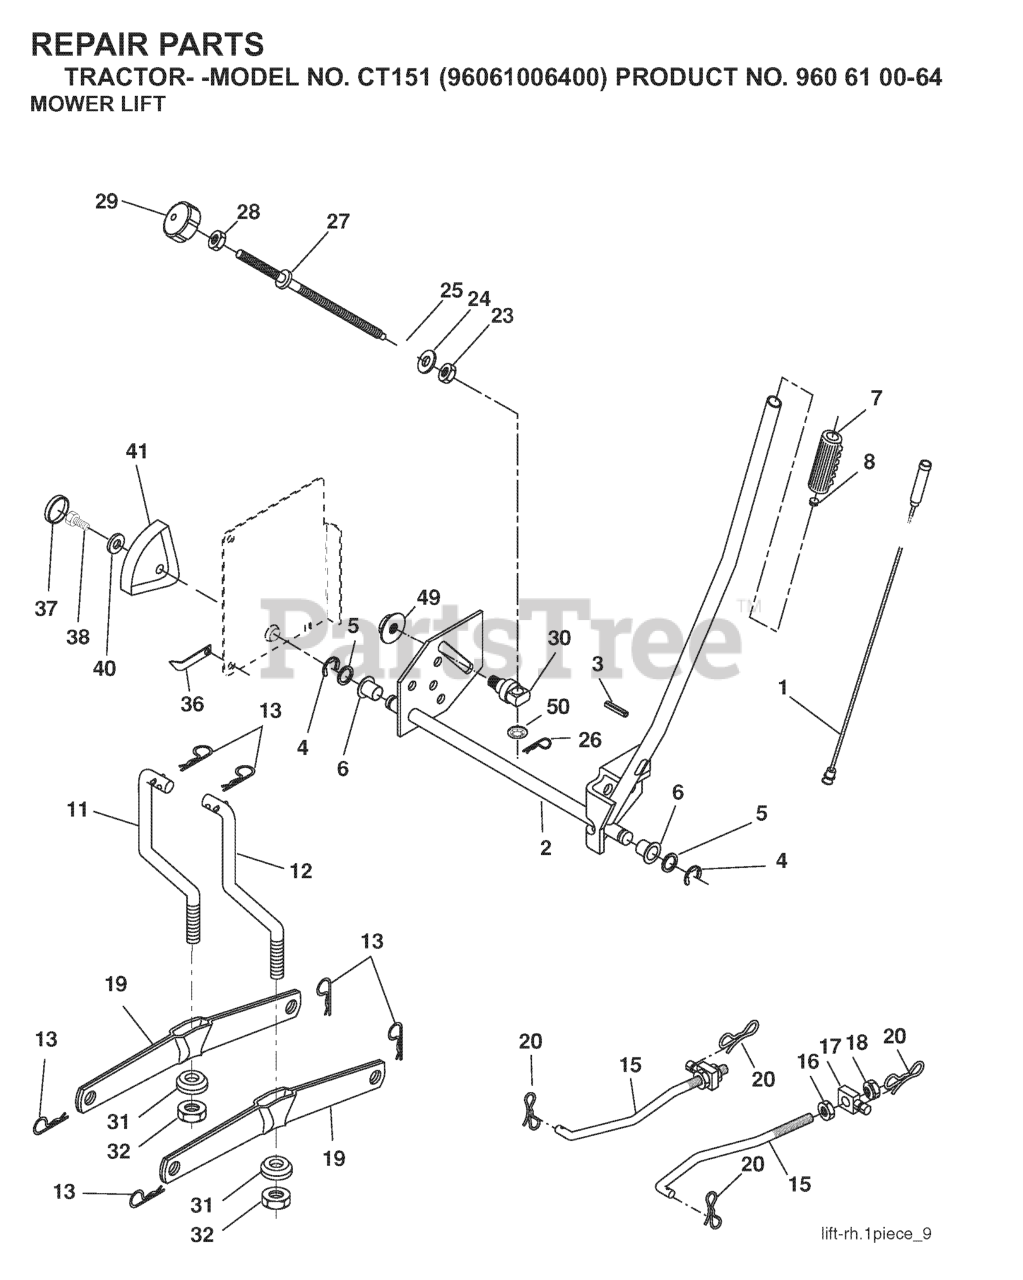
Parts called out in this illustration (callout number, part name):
1	WIRE ASM INNER W/ PLUNGER LT
2	SHAFT ASM R HANDLE
3	PIN GROOVE.
4	RETAINING RING LT
6	BEARING.NYLON
7	GRIP HANDLE
8	PLUNGER BUT KIT
11	LINK
12	LINK
13	RETAINER-SPRNG RB
15	LINK.SUSPENSION.FRONT
16	NUT.HEX.JAM.1/2-13
18	NUT.LK.W/WSH.1/2.
19	ARM.REAR.SUSPENSION
20	PIN.COTTER.7/16.BOW TI.
25	SPRING**
26	RETAINER CLIP
27	ROD ADJ LIFT
28	NUT
29	KNOB INF 3/8-16
31	BEARING.PIVOT.LIFT
32	NUT CROWNLOCK 3/8-24
36	POINTER, HEIGHT INDICATOR(2 2)
38	SCREW 5/16-18X1
41	HEIGHT INDICATOR
49	NUT
50	NUT PUSH M
